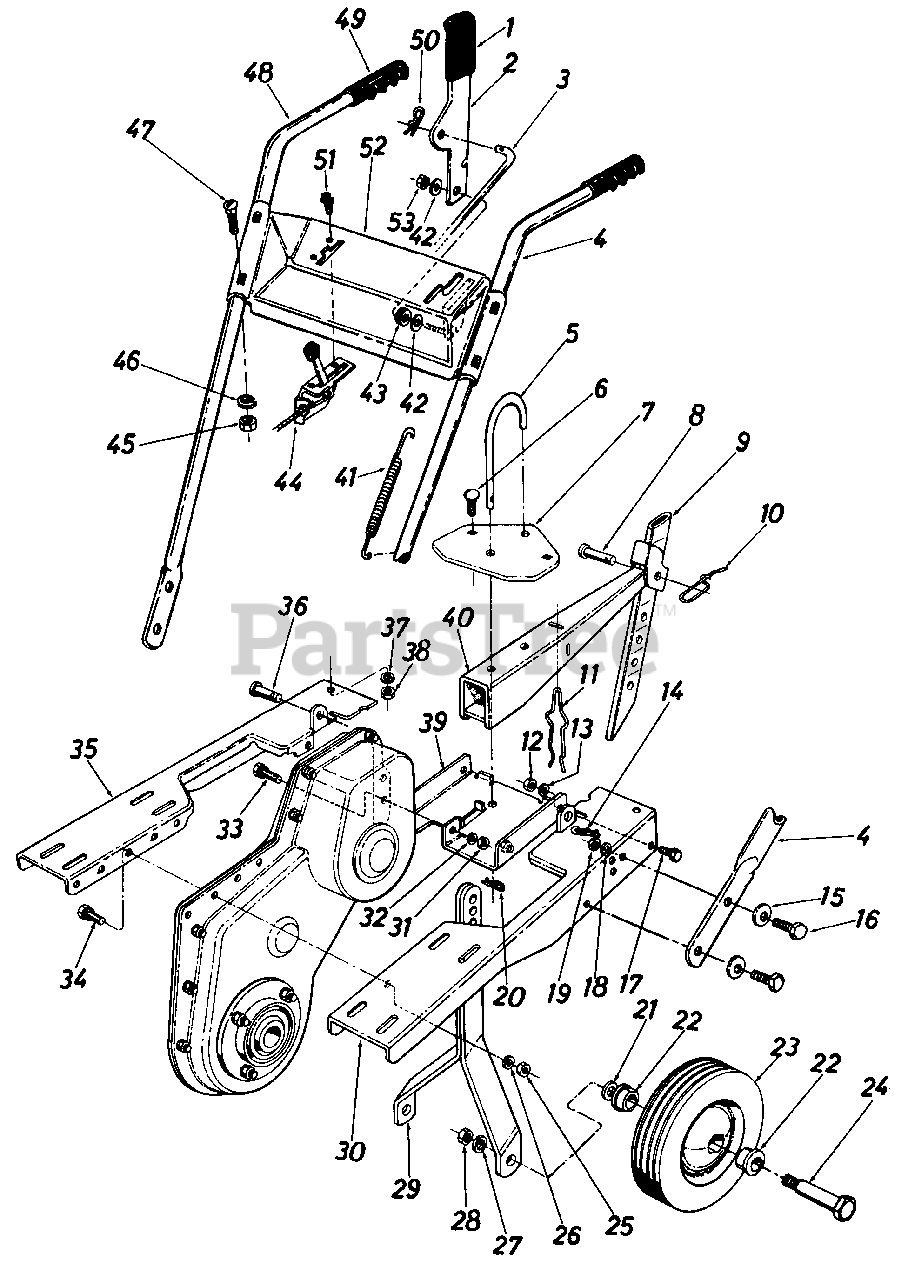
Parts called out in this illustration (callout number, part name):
2	Clutch Lever
3	Clutch Control Rod
4	Handle - L.H.
5	"U"-Clevis Pin .500" Dia.
6	Carriage Bolt 5/16-18 x .75" Lg.
7	"U" Channel Plate
8	Clevis Pin 1/2" Dia.
9	Depth Bar
10	Spring Pin
11	Depth Bar Spring
12	Hex Nut 5/16-18 Thd.
13	L-Wash. 5/16" I.D.
14	Int. Cotter Pin 1/2" Dia.
15	Belleville Wash. 3/8" I.D.
16	Hex Bolt 3/8-16 x 1.00" Lg.
17	Hex Sems Bolt 5/16-18 x .75" Lg.
18	L-Wash. 3/8" I.D.
19	Hex Nut 3/8-16 Thd.
20	Int. Cotter Pin 1/2" Dia.
21	Belleville Wash.
22	Flange Bearing
23	Wheel Ass'y. Comp. 10 x 2.75
24	Shoulder Bolt .625" Dia. x 2.75" Lg. (1/2-20 Thd.)
25	Hex Nut 5/16-18 Thd.
26	L-Wash. 5/16" I.D.
27	L-Wash. 1/2" I.D.
28	Hex Cent. L-Nut 1/2-20 Thd.
29	Wheel Bracket Ass'y.
30	Engine "U"-Channel Ass'y. - L H.
31	Hex Nut 5/16-18 Thd.
32	L-Wash. 5/16" I.D.
33	Hex Sems Bolt 5/16-18 x 1.00" Lg.
34	Hex Sems Bolt 5/16-18 x 1.00" Lg.
35	Engine "U"-Channel Ass'y. - R.H.
36	Clevis Pin
37	L-Wash. 5/16" I.D.
38	Hex Nut 5/16-18 Thd.
39	"U"-Channel Bracket Ass'y.
40	Tailpiece Assembly
41	Extension Spring
42	Fl-Wash. .380" I.D.
43	Rubber Washer
44	Throttle Control Ass'y. Comp.
45	Hex Nut 5/16-18 Thd.
46	L-Wash. 5/16" I.D.
47	Carriage Bolt 5/16-18 x .75" Lg.
48	Handle - R.H.
49	Grip - Handle
50	Int. Cotter Pin 1/2" Dia.
51	Hex Wash. Hd. AB-Tap Scr. #8 x .62" Lg.
52	Handle Panel
53	Hex Inst. L-Nut 3/8-24 Thd.
